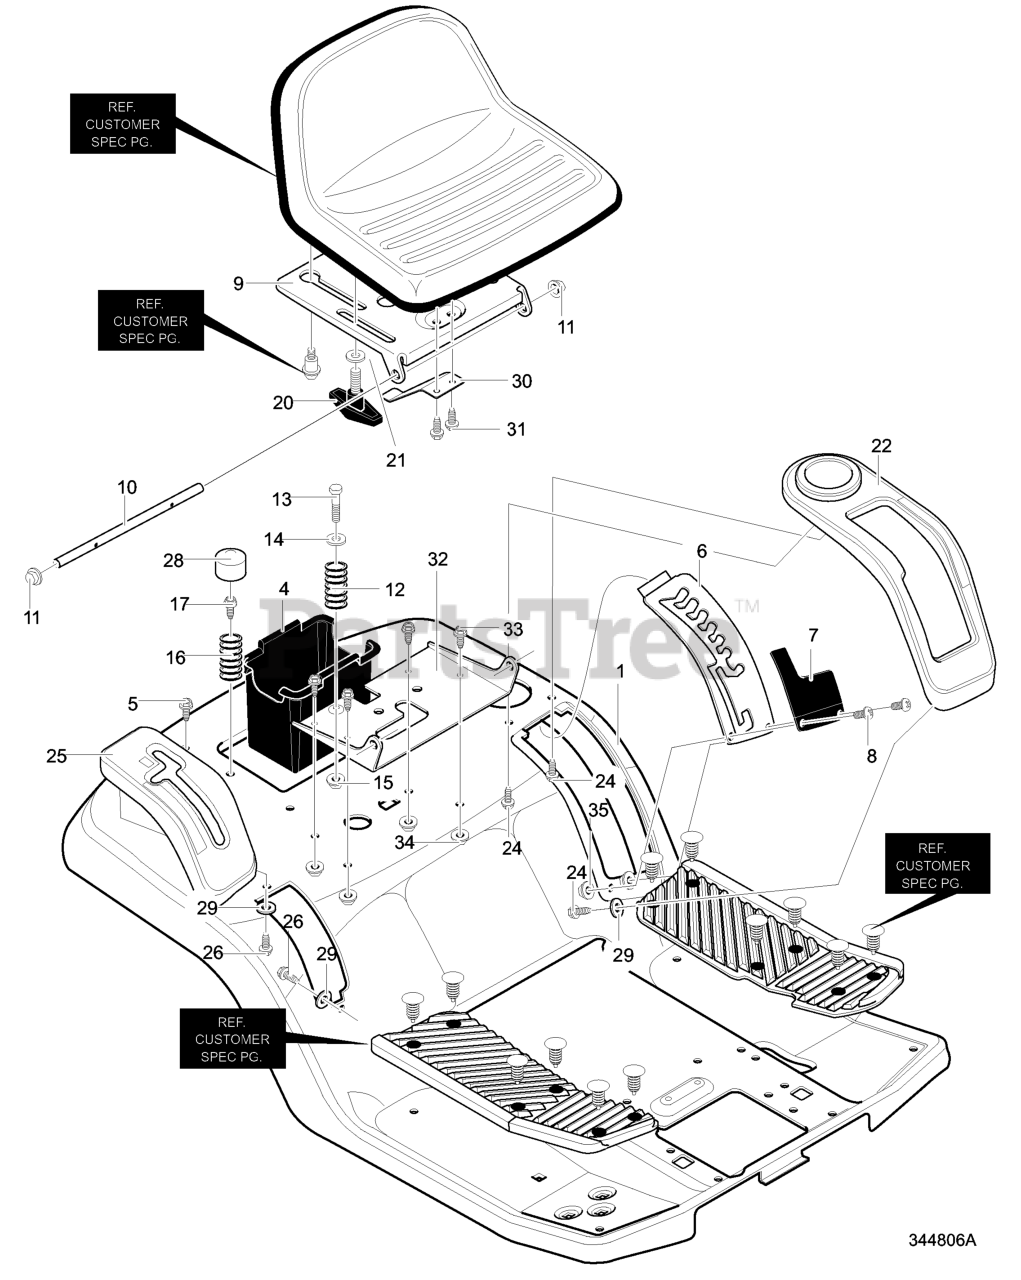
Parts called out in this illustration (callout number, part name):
1	SEAT DECK-LARGE
4	CONTAINER, BATTERY
5	SCREW, 1/4-20X .63
6	PLATE LIFT DETENT
7	LIFT DET LOCKOUT LG GREY
9	SUPPORT, SEAT
10	HINGE SEAT PIVOT
11	NUT, PUSH CAP
12	SPRING, COMPRESSION
13	BOLT, SHOULDER
14	WASHER CUP
16	SPRING, COMPRESSION
20	BOLT, WING
21	WASHER, FLAT
22	DETENT COVER W/CUP
25	SHIFT COVER
26	SCREW, 1/4-15X0.44
27	WASHER, FLAT
28	CAP, HUB/SEAT SPRING
29	WASH, FLAT
30	SPRING - LEAF
31	SCREW, 1/4-20X.50
32	BRACKET, PIVOT SEAT
33	SCREW 5/16-18X.75
34	NUT, 5/16-18
35	NUT, #10-32
